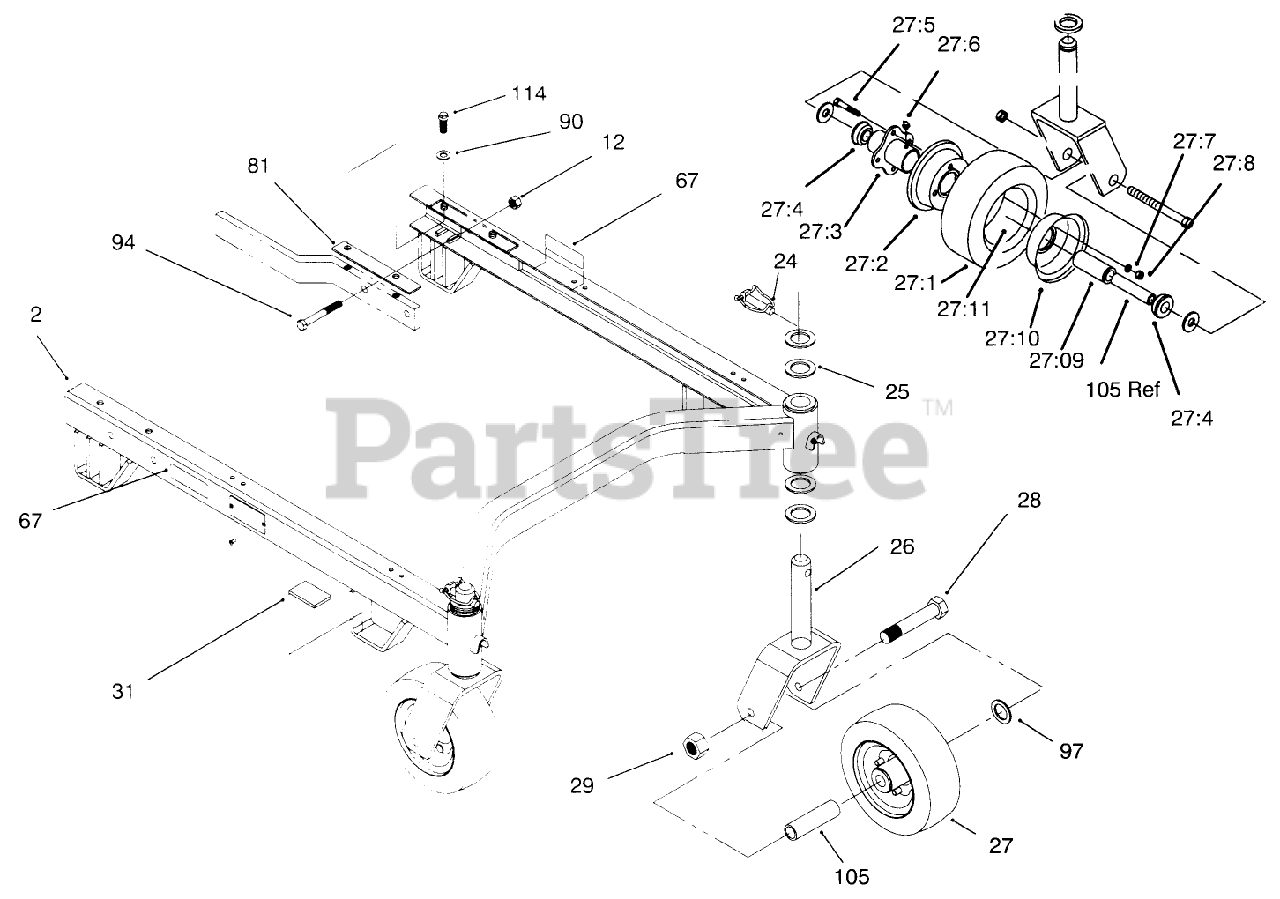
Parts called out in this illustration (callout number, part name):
2	SUSPENSION W A
12	NUT-LOCK, CONE
24	PIN-LYNCH
25	WASHER-THRUST
27:2	FEMALE WHEEL HALF
27:3	HUB-CENTER
27:4	BEARING-OUTSIDE
27:5	WHEEL BOLT
27:6	FITTING-GREASE
27:7	SCREW-HH
27:8	NUT-HEX
27:09	BEARING-ROLLER
27:10	MALE WHEEL HALF
27:11	TUBE-INNER (W/VALVE)
28	SCREW-HH
29	NUT-HEX
31	CUSHION-RUBBER
67	DECAL-HOC
81	SHIM-CARRIER
90	WASHER-FLAT
94	SCREW-HH
97	WASHER-FLAT
105	SPANNER-TIRE
114	SCREW-HHF
